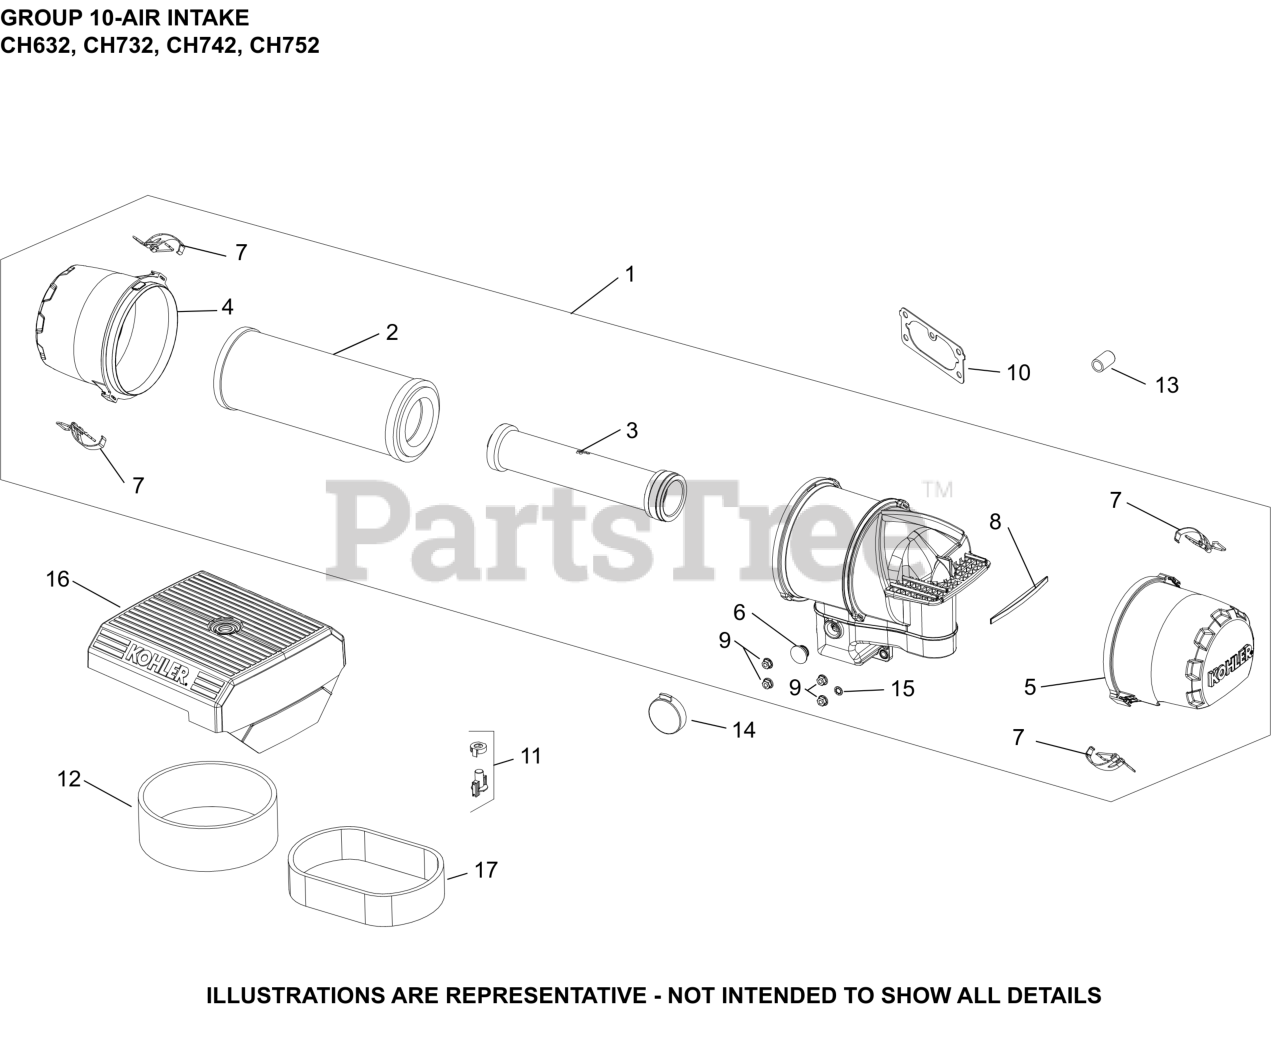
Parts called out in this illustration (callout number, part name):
1	KIT, AIR CLEANER
2	ELEMENT, AIR FILTER - PRIMARY
3	ELEMENT, AIR FILTER - SAFETY
4	COVER, AIR FILTER
5	COVER, RAIN CAP
6	PLUG, HOLE
7	CLIP ASSEMBLY
8	DAMPER, FOAM INSERT
9	NUT, FLG M6X1.0
10	GASKET, AIR CLEANER
15	WASHER, INT TOOTH LOCK 1/4"
NI	SCREW, HEX FLANGE
